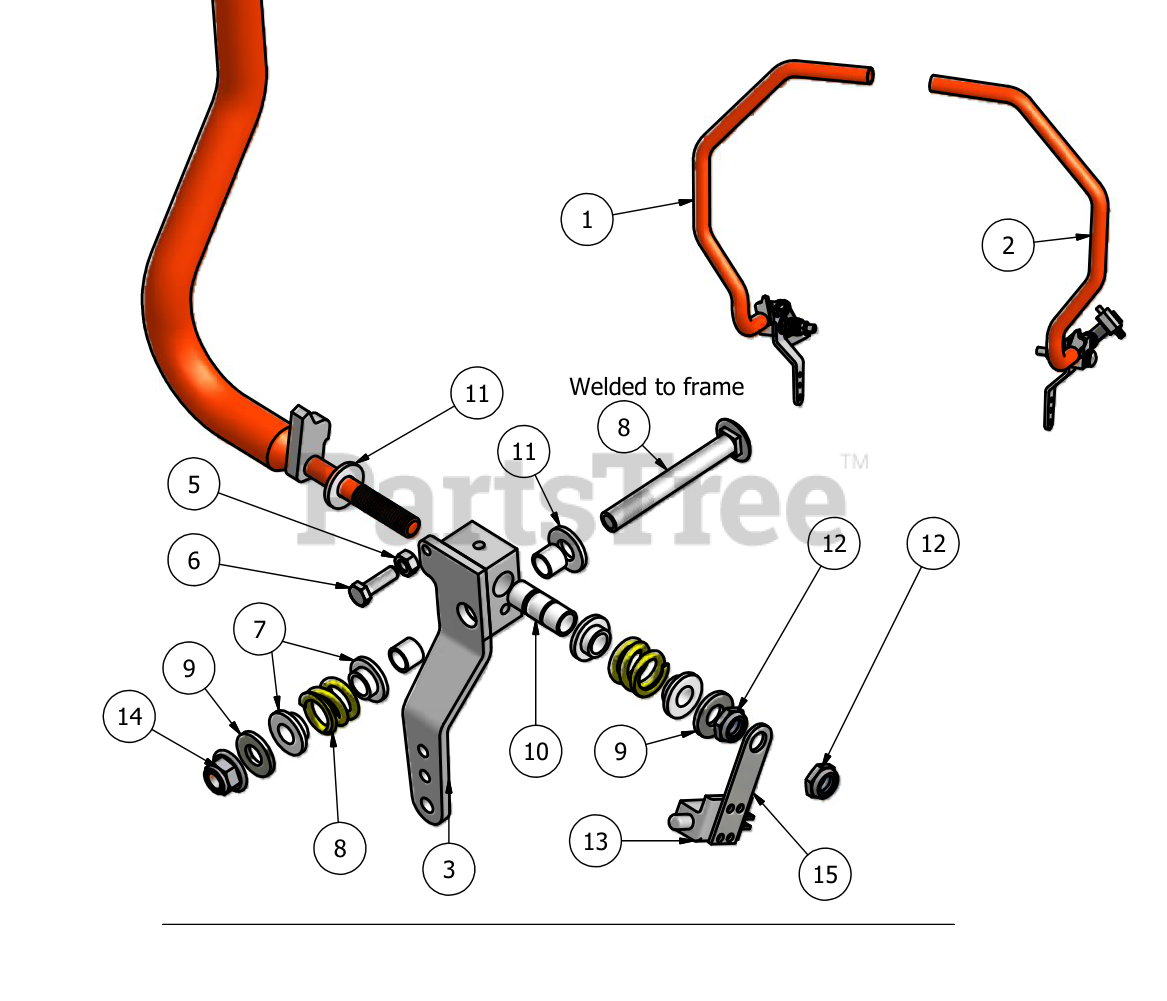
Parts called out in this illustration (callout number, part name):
1	Right Drive Lever
2	Left Drive Lever
3	Drive Arm Lever Housing - Right
4	Drive Arm Lever Housing - Left
5	5/16" Hex Nut
6	5/16"x 3/4" Hex Bolt
7	Nylon Washer .515 ID Shoulder
9	7/16 Flat Washer
10	Nylon Bushing .507 ID
11	.505 Nylon Washer
12	1/2" Nylcock Nut (1/2 Jam)
13	Electric Saftey Switch
14	1/2" Flange Lock Nut
15	Switch Bracket
